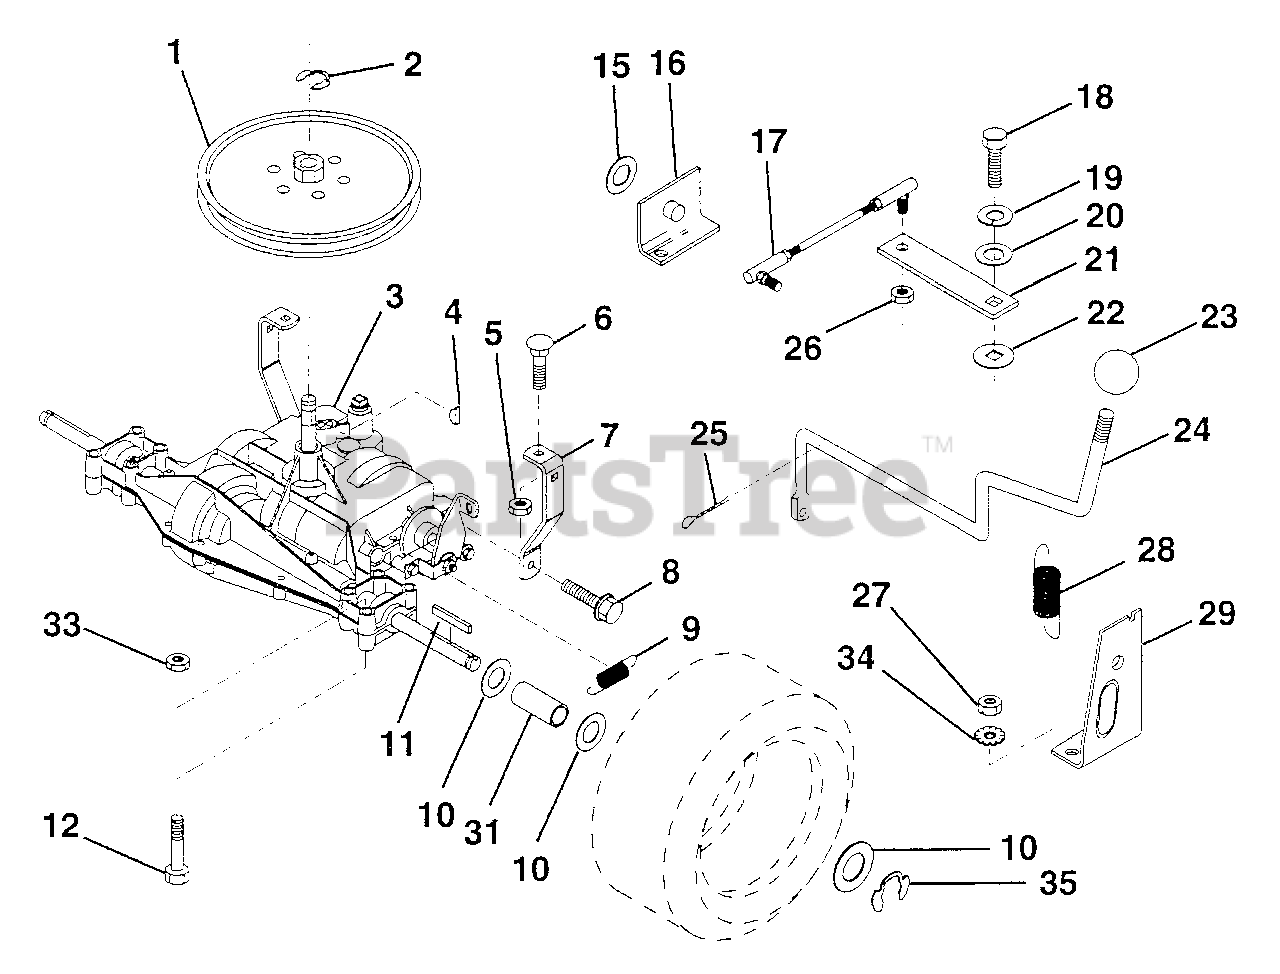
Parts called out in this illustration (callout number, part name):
2	Ring, Retainer
3	Transaxle, Dana 4-Speed Model #D4360-46
4	Key, Woodruff #9
5	Nut, Crownlock 5/16-18
6	Bolt, Carriage 5/16-18 UNC x 3/4
7	Strap, Torque
8	Screw 5/16-18 x 3/4
9	Spring, Brake
10	Washer 25/32 x 1-1/4 x 16 Ga.
11	Key, Square
12	Bolt, Fin Hex 3/8-16 x 2-3/4
15	Washer 17/32 x 1 x 16 Ga.
16	Support, Handle, Shift L.H.
17	Link, Shift
18	Bolt, Fin Hex 1/4-28 UNF x 3/4 Gr. 8
19	Washer, Lock 1/4
20	Washer 9/32 x 3/4 x 10 Ga.
21	Arm, Shift
22	Washer, Shift Plate
23	Knob, Golf Club
25	Pin, Cotter 1/8 x 1
26	Nut, Hex Nylon
27	Nut, Keps 5/16-18
28	Extension, Spring
29	Support, Handle, Shift R.H.
31	Spacer, Split
33	Nut, Crownlock 3/8-16
34	Washer, Ext. Tooth, Lock 5/16
